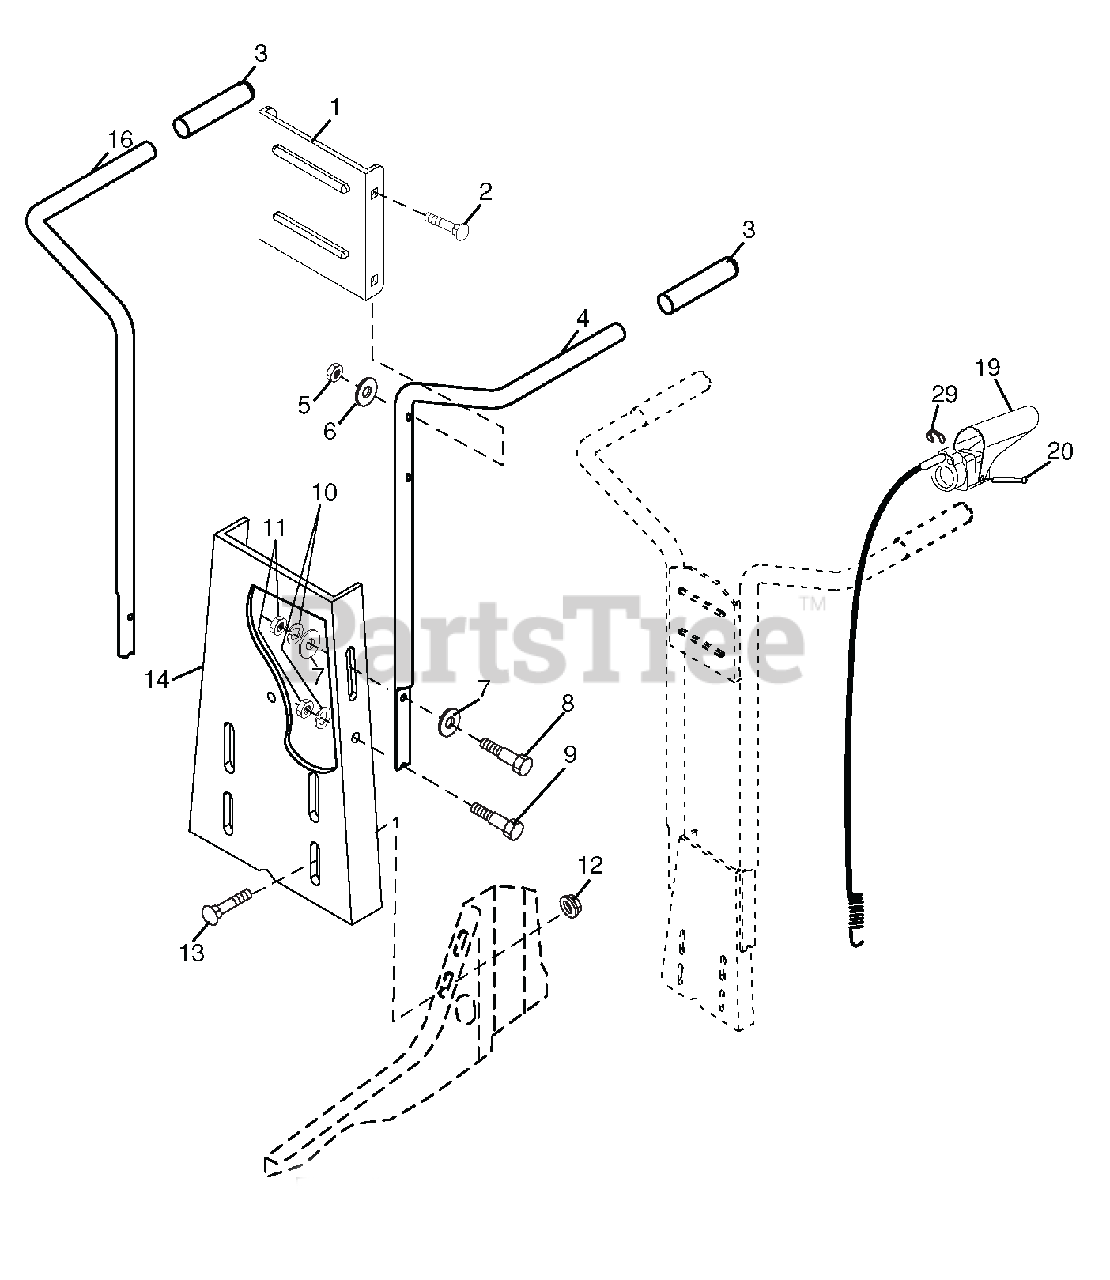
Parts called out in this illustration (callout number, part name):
1	Bracket, Handle
2	Bolt, Carriage 5/16-18 x 1-1/2
3	Grip, Handle
4	Handle, L.H.
5	Nut, Hex, Crownlock 5/16-18
6	Washer 11/32 x 11/16 x 16 Ga.
7	Washer 3/8 x 7/8 x 14 Ga.
8	Bolt, Hex Head 5/16-18 x 1-1/4
9	Bolt, Hex Head 5/16-18 x 1
10	Washer, Lock 5/16
11	Nut, Hex 5/16-18
12	Nut, Hex, Flanged 5/16-18
13	Bolt, Carriage, Gr. 5 5/16-18
14	Panel, Handle
16	Handle, R.H.
19	Tine Control Lever Assembly (I
20	Pin, Pivot
29	Retaining Ring
